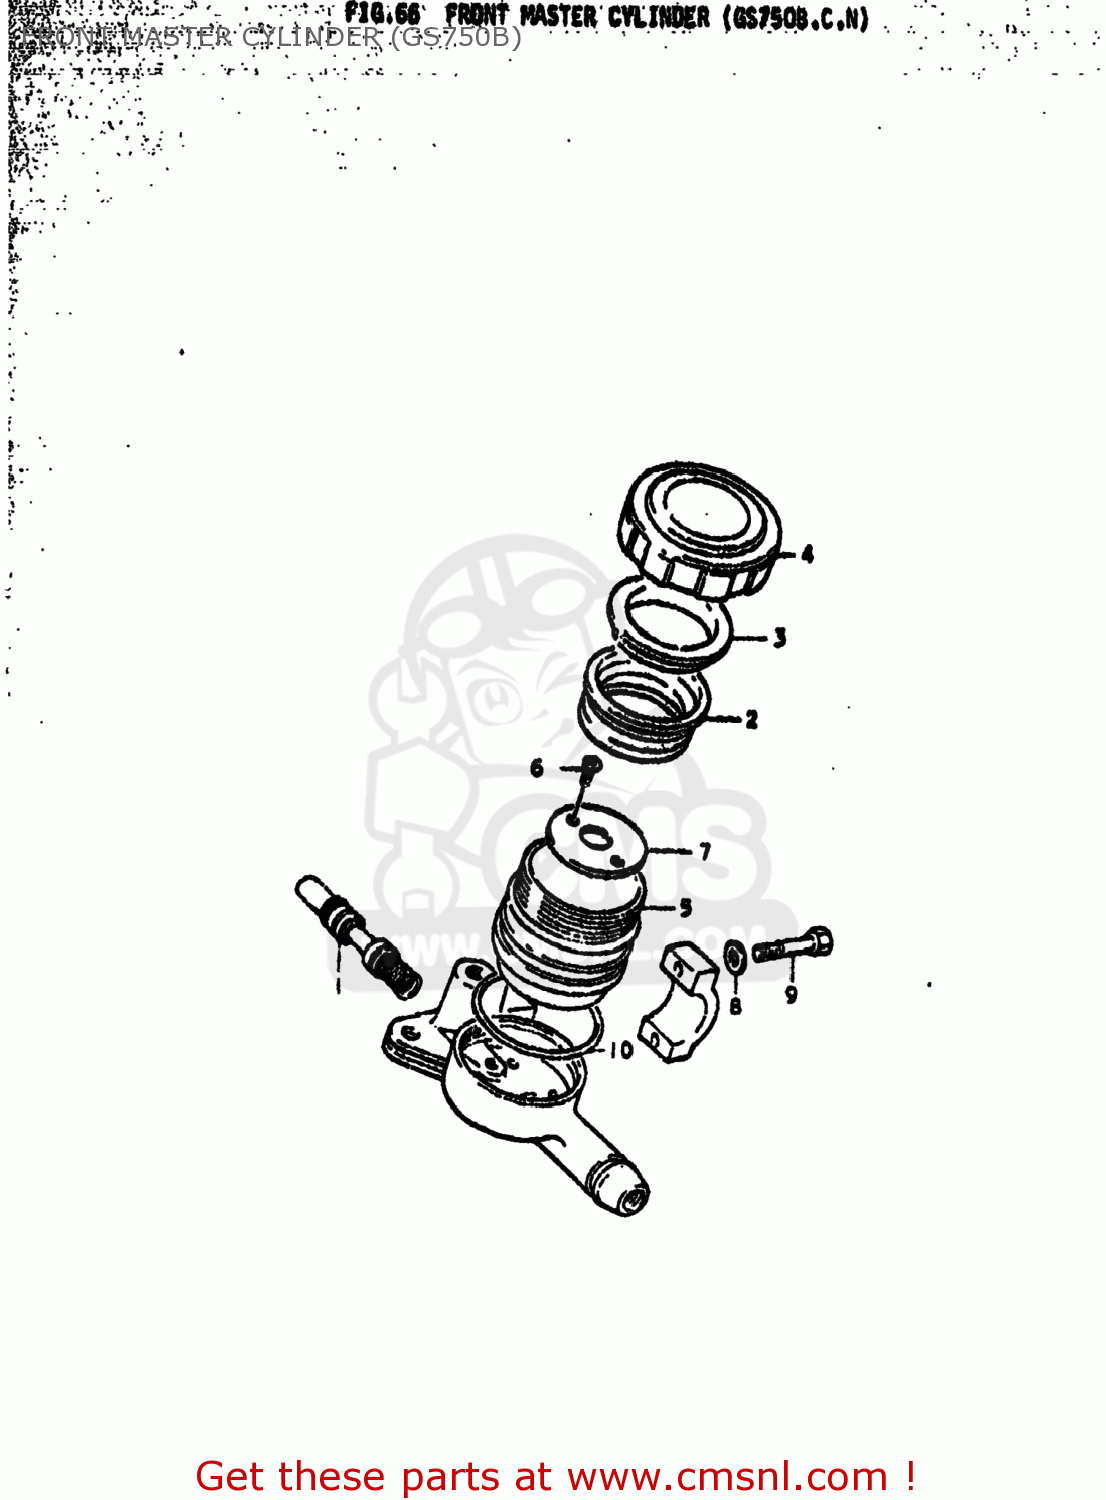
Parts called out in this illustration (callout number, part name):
1	PISTON & CUP SET
2	DIAPHRAGM
3	PLATE
4	CAP,MASTER CYLINDER,REAR
5	RESERVOIR,MASTER CYLINDER
6	SCREW,MASTER CYLINDER
7	BOLT
8	WASHER
9	O RING
